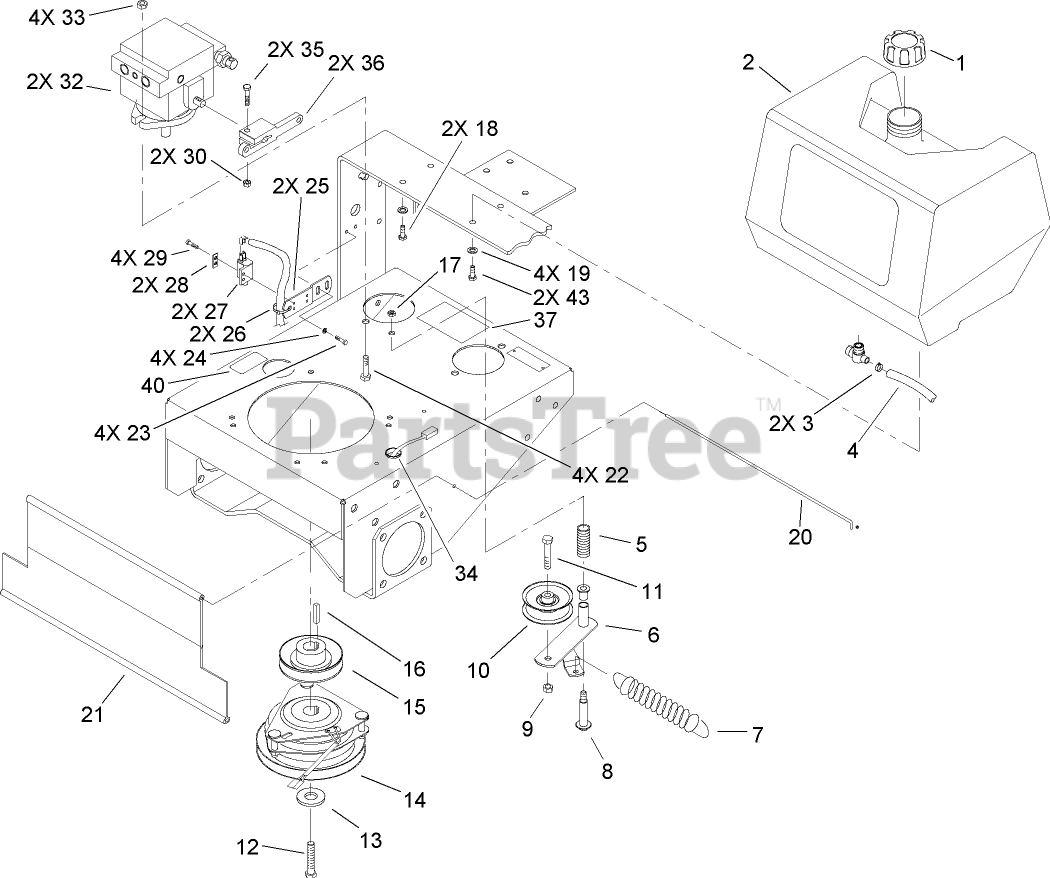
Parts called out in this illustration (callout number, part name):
1	GAS CAP ASM
2	TANK-FUEL
3	CLAMP-HOSE
4	HOSE-FUEL
5	SPRING-COMPRESSION
6	IDLER LEVER ASM
7	SPRING
8	BOLT-WHEEL
9	NUT-LOCK, NI
10	PULLEY
11	SCREW-HH
12	SCREW-HH
13	WASHER
14	CLUTCH / BRAKE ASM
15	Pulley
16	KEY-SQUARE
17	NUT-LOCK
18	SCREW-HH
19	WASHER-LOCK
20	ROD-SHIELD
21	SHIELD-TRAILING
22	SCREW-HH
23	SCREW-HWH
24	WASHER-FLAT
25	Bracket-Neutral
26	TIE-CABLE
27	SWITCH-POLE, SINGLE
28	PLATE-SWITCH
29	SCREW-TAPTITE
30	NUT-LOCK, NI
32	HYD PUMP ASM
33	NUT-HF
34	GROMMET
35	SCREW-HH
36	ARM-PUMP
37	DECAL-ADJUSTMENT, VALVE
40	DECAL-STD, SAFETY
43	SCREW-HH
